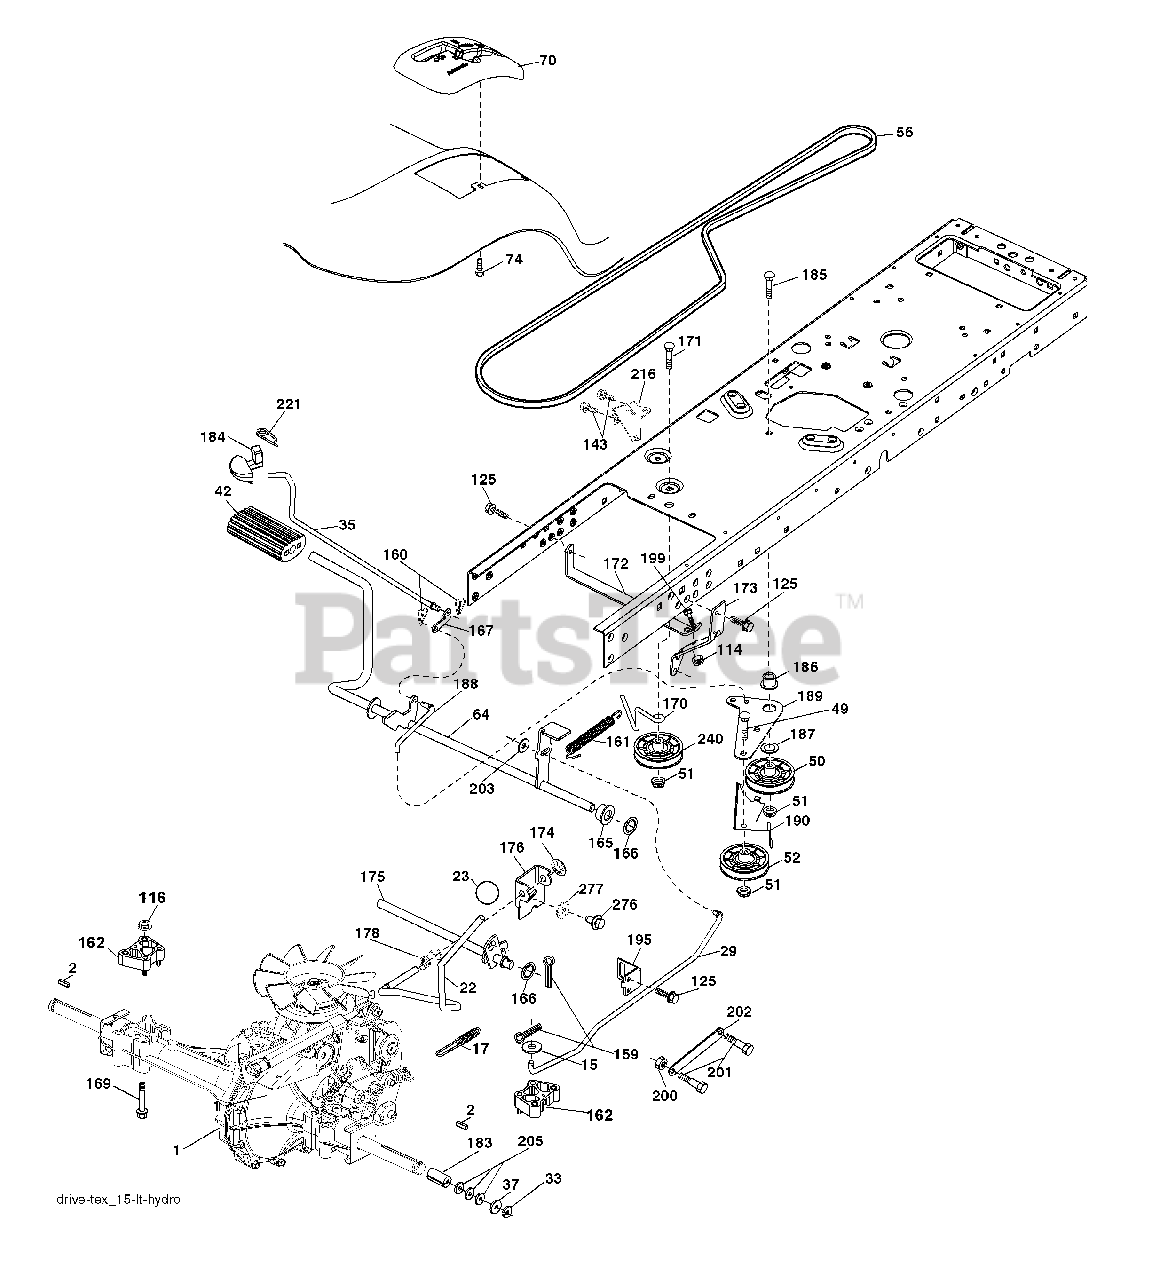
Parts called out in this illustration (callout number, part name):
15	Washer 13/32 x 13/16 x 16 Ga.
17	Spring, Brake
29	Rod, Brake
35	Rod, Brake, Park
37	Washer 25/32 x 1-1/4 x 16 Ga.
42	Cover, Foot Pedal
50	Pulley Idler Flat
51	Lock Nut 3/8-16
52	Idler V-Groove 910" Offset
56	V-Belt, Drive
64	Shaft Asm. Pedal Brake Control
70	Console Shift
73	Bolt Hex Flghd 5/16-18 Gr. 5
74	Screw Hex WSH Hi-Lo 1/4 x 1/2 unc
114	Nut Lock Hex w/INS 5/16-18 unc
116	Nut Lock Hex Flange 5/16-18
125	Screw 5/16-18 x 3/4
143	Screw 5/16-18 x 1/2
159	Pin Cotter 1/8 x 3/4
160	Retainer Clip
161	Spring, Return, Clutch
162	Spacer Transaxle
166	Nut Push .625
167	Latch Brake Parking
169	Bolt 5/16-18 x 3.75
170	Keeper Belt Centerspan
172	Strap Torque LH
173	Strap Torque RH
176	Asm Clevis Rod Shift
178	Spring Shift
183	Spacer Axle
184	Handle Parking Brake
186	Spacer Retainer
187	Washer
188	Link Clutch Ground Drive
189	Bellcrank Ground Drive
190	Keeper Bellcrank Ground Drive
195	Bracket Rod Brake
199	Bolt RDHD SQNK 5/16-18 unc x 1
200	Nut Center Lock 5/16-18 unc
201	Bolt Shoulder 5/16-18 unc
202	Link Trans
203	Washer 11/32 x 11/16 x 16 Ga.
205	Washer 25/32 x 1-5/8 x 16 Ga.
216	Bracket Pulley
221	Retainer Spring Clip Handle
240	Pulley V-Groove
276	Bolt 7/16-14 x 1
277	Washer Serrated
